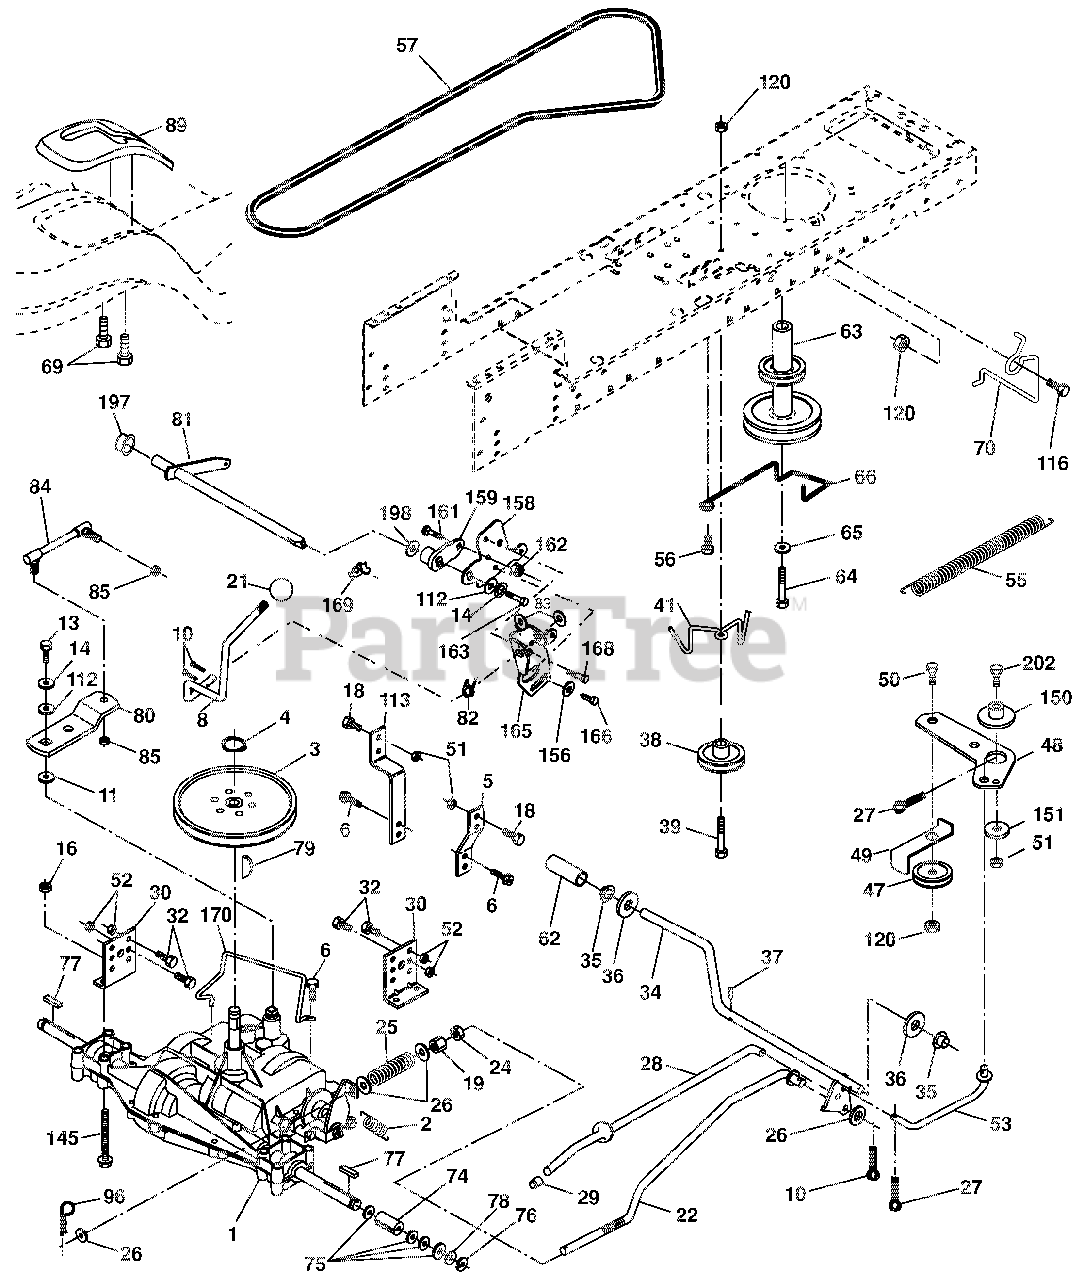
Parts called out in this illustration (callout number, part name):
1	TRANSAXLE PEERLESS 206-545C (165670) (ORDER PARTS FROM TRANSAXLE MANUFACTURER.)
2	Spring Return Brake T/a Zinc
3	PULLEY.TRANSAXLE.18/20"TIRES
4	Ring, Retainer
5	Strap Torque 30 Degrees
6	SCREW.5/16-18X3/4.SMGML.TAP/R
8	Rod Shift Fender Adjust Lt
10	Pin Cotter 1/8 x 1 Cad
11	WASHER.PLATE.SHF..388 SQ.HOLE
13	BOLT.1/4-28 UNF.GR8.W/PATCH
14	Washer, Lock 1/4
16	Locknut, Washer Insert 5/16-18
18	Bolt, Fin Hex 3/8-16 unc x 1
19	Locknut, Washer Insert 3/8-16
22	Rod Brake Blk Zinc 26 840
24	Nut, Hex, Jam 3/8-16
25	Spring Rod Brake 2 00 Zinc
26	WASHER.13/32 X 13/16 X 16 GA.
27	PIN.COTTER.1/8 X 3/4.CAD.
28	Rod Brake Parking LT/YT
29	Cap Brake Parking
30	BRACKET
32	Bolt, Hex Head 5/16-18 x 3/4
34	Shaft Asm Pedal Foot
35	BEARING.NYLON.BLK..629 ID.
36	Washer 21/32 x 1 x 16 Ga.
37	PIN.ROLL.3/16X1
38	Pulley Composite Flat
39	BOLT.RDHD.3/8-16UNC X2-3/4 GR5
41	Keeper Belt Flat Idler
47	Pulley Idler V Groove
48	Bellcrank Asm
49	Retainer Belt Style Spring
50	BOLT.CARR.SH.3/8-16X1-1/2.GR5
51	Nut, Hex, Crownlock 3/8-16
52	Nut, Hex, Crownlock 5/16-18
53	Link Clutch
55	SPRING.RETURN.CLUTCH.6.75
56	Screw 3/8-16 x <
57	V-Belt Ground Drive
62	COVER PEDAL BLK ROUND
63	Engine Pulley
64	BOLT.HEX.7/16-20X4XGR5-1.5THR.
65	WASHER.LOCK.HVY HLCL.SPR.7/16
66	Keeper Belt Engine Foolproof
69	SCREW.HEX.WSH.HI-LO.1/4X1/2UNC
70	Guide Belt Mower Drive RH
74	SPACER.AXLE.HYDRO/PEERLES
75	WASHER.25/32 X 1 1/4 X 16 GA.
76	E-RING.#5133-75
77	KEY.SQUARE.2.0 X .1845/.1865
78	WASHER.25/32 X 1-5/8 X 16GA.
79	KEY.WOODRUFF
80	ARM.SHIFT
81	BRACKET
82	Spring Torsion T/a
83	Washer 17/32 x 3/4 x 16 Ga.
85	NUT.LOCK.CENTER.1/4-28 FNTHD.
89	CONSOLE.SHIFT
96	RETAINER SPRING
112	WASHER.9/32 X 3/4 X 10 GA.
113	Strap Torque LT
116	Bolt, Carriage 3/8-16 x 1
120	Nut, Hex, Flangelock 3/8-16
145	BOLT 5/16-18 X 2 1/2 G.5
150	Spacer Retainer
151	WASHER.13/32 X 2 X 10 GA.
156	Washer Srrted 5/16ID x 1.125
158	BRACKET
159	HUB.SHIFT
161	Bolt Rdhd Sqnk 1/4-20 x 3/4
162	Nut Crownlock 1/4-20 unc
163	Bolt Hex Fin 1/4-20 unc x 1 Gr
165	BRACKET
166	Screw 5/16-18 x 5/8
168	Bolt Shoulder 5/16-18 x .561
169	Plate Fastening
170	Keeper Belt Transaxle Gear
197	Nyliner Snap-In
198	Washer Nyliner
202	BOLT.RDHD.3/8-16UNCX1-3/4.GR5
